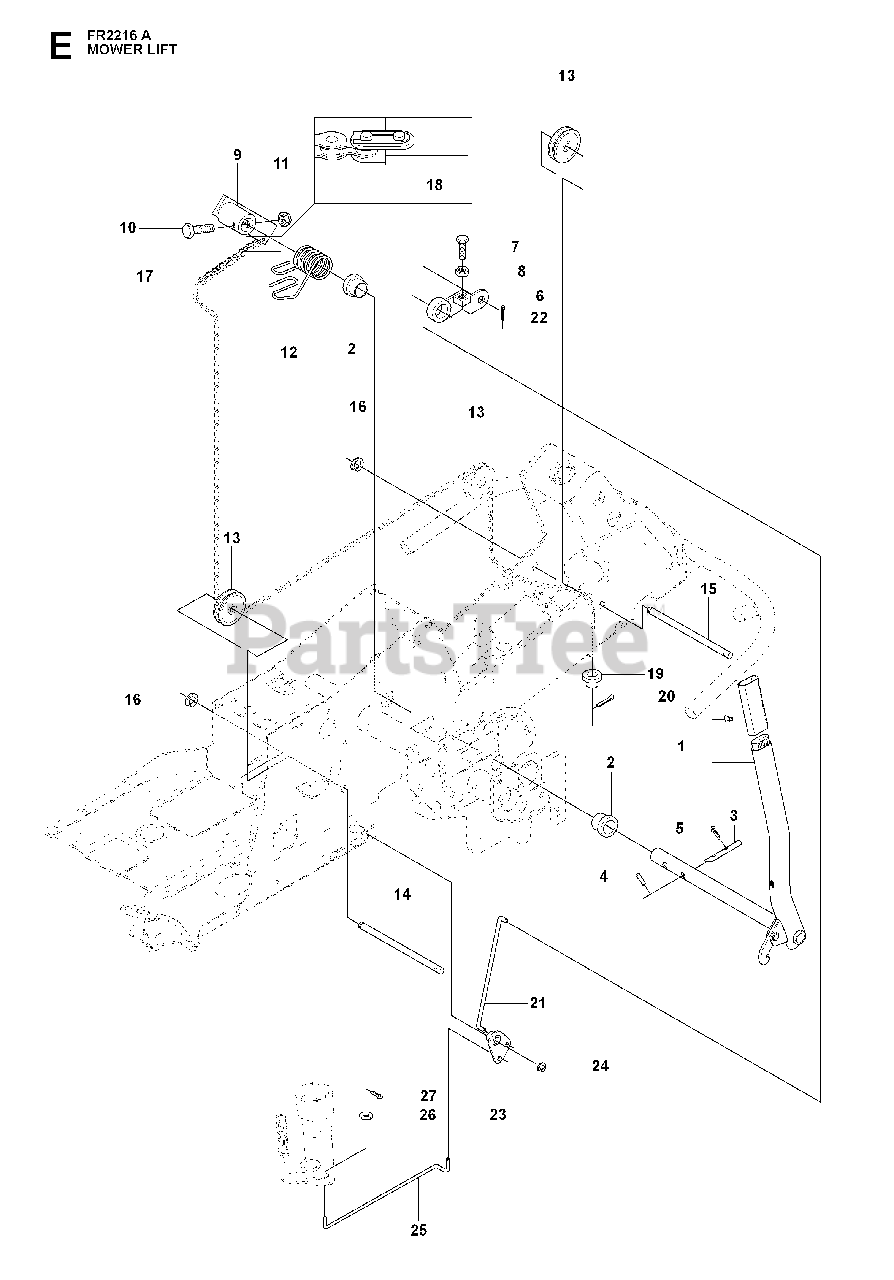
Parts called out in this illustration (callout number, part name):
1	LIFTING LEVER ASSY
2	BUSH
3	RP PIN
5	SPLIT PIN
6	LEVER CLUTCH
16	LOCK RING
20	COTTER PIN
21	CONNECTION ROD
22	SPLIT PIN
24	RETAINING RING
25	CONNECTION ROD
27	SPLIT PIN
